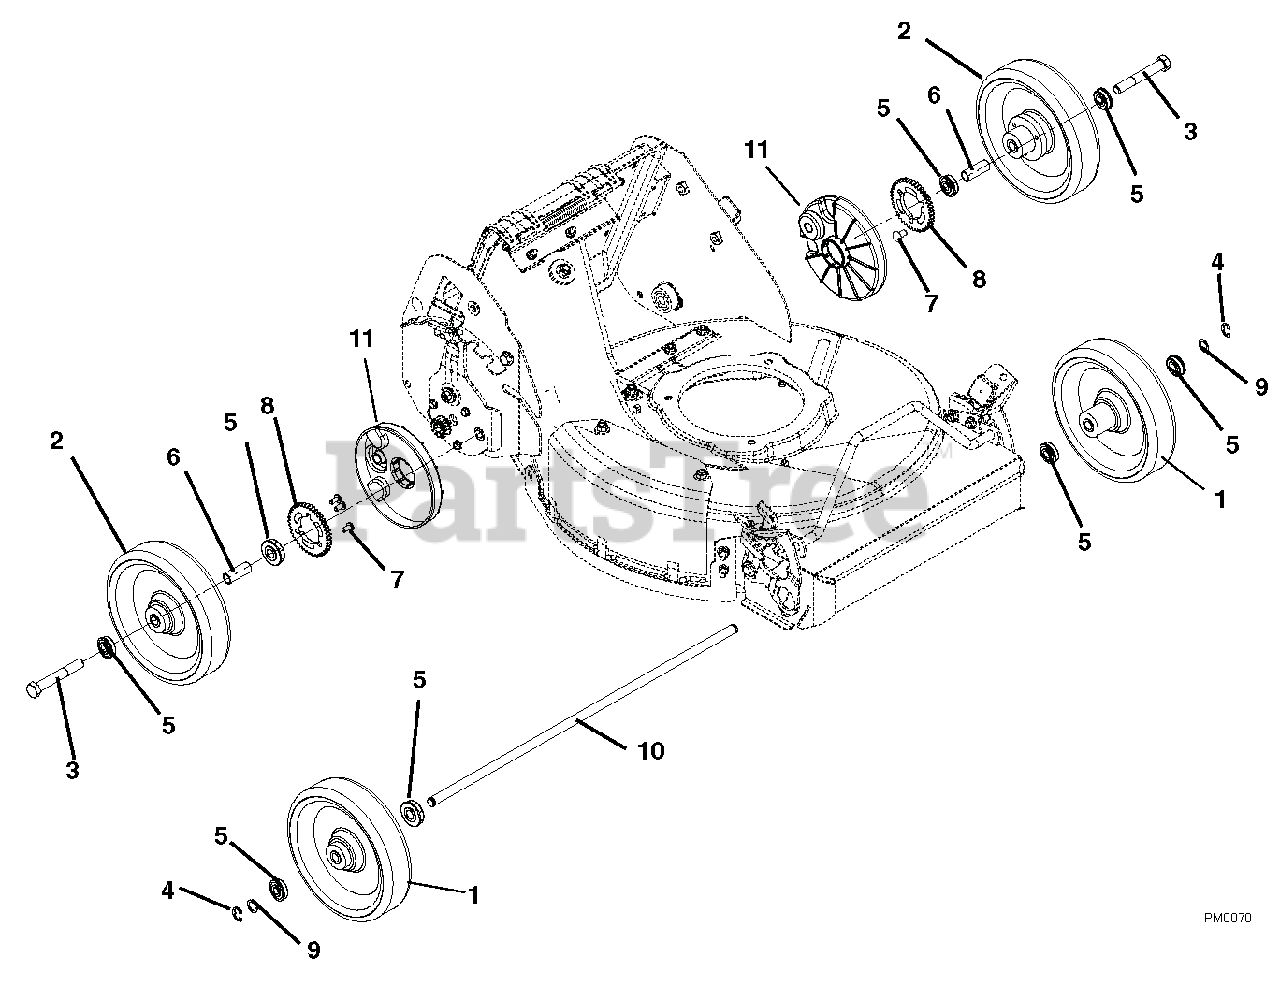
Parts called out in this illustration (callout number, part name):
1	TIRE, 8 X 1.75 COMMERCIAL FRNT
2	TIRE, 8 X 1.75 COMMERCIAL REAR
3	BLT-HEX .50-13X3.50 GR8 YWZC
4	RG-RTNG-EXT .500X.042 (E)
5	BRG-BALL .50X1.38X.438 SEALED
6	SPACER,.560 ID X.750 OD X 2.09
7	SCR-TAP 1/4-20X3/4 LPAN TL BZ
8	GEAR, WHEEL
9	WASHER, .500X.750X.020 THRUST
10	AXLE, HD21 FRONT
11	COVER, WHEEL
